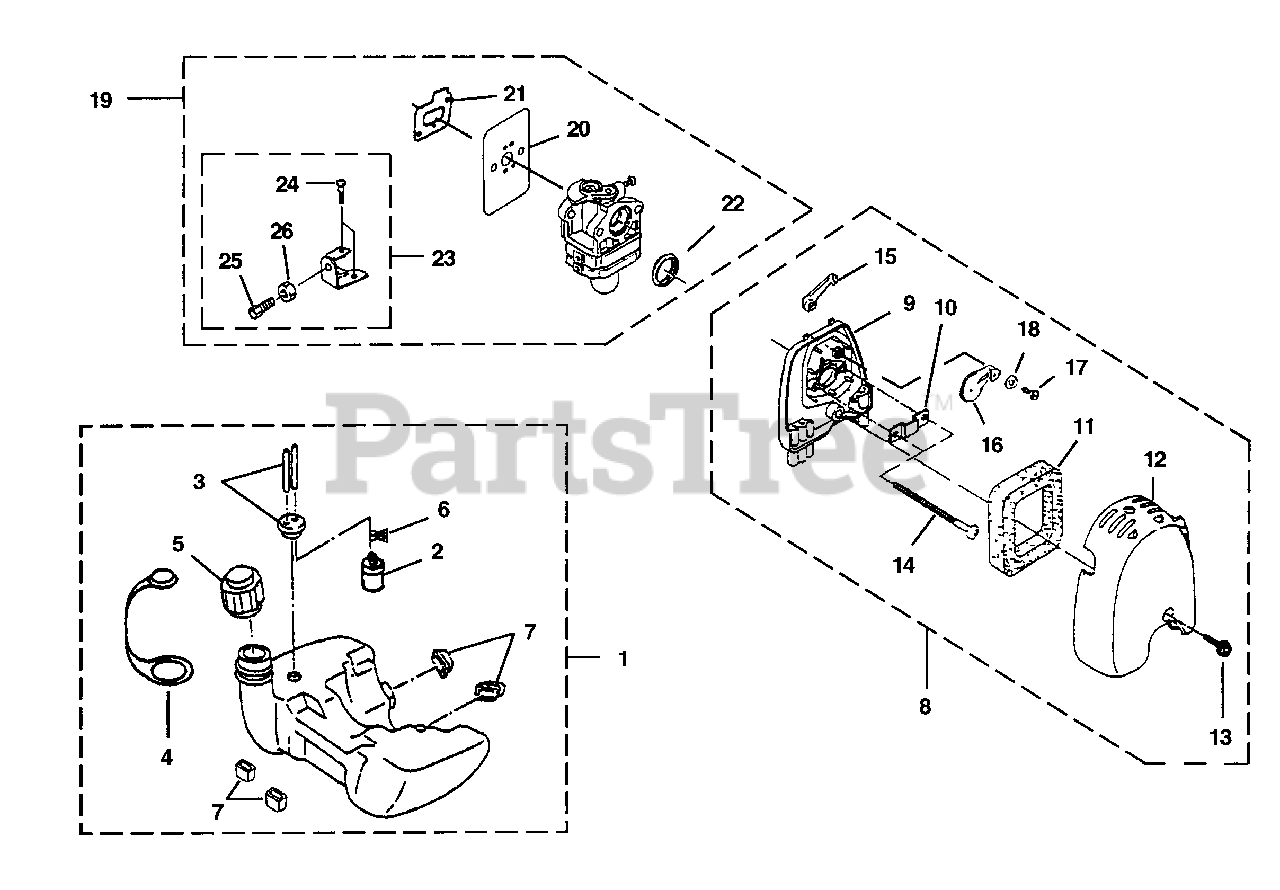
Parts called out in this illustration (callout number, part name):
1	FUEL TANK ASSEMBLY
2	FILTER-Fuel
4	CAP-Retainer
5	CAP-Fuel
6	CLAMP-Hose
7	RUBBER BUMPER KIT
8	AIR FILTER ASSEMBLY
9	BODY-Air Filter
10	PLATE-Air Filter
11	FILTER-Air
12	COVER-Air Filter
13	SCREW ASSEMBLY (M5 x 14)
14	SCREW
15	LEVER-Choke
16	PLATE-Choke
17	SCREW-Tapping
18	WASHER
19	CARBURETOR ASSEMBLY
20	GASKET-Carburetor
21	GASKET-Heat Dam
22	RING-Packing
23	CABLE BRACKET ASSEMBLY
24	SCREW-Throttle Collar
25	SCREW-Cable Adjust
26	NUT-Cable Adjust
